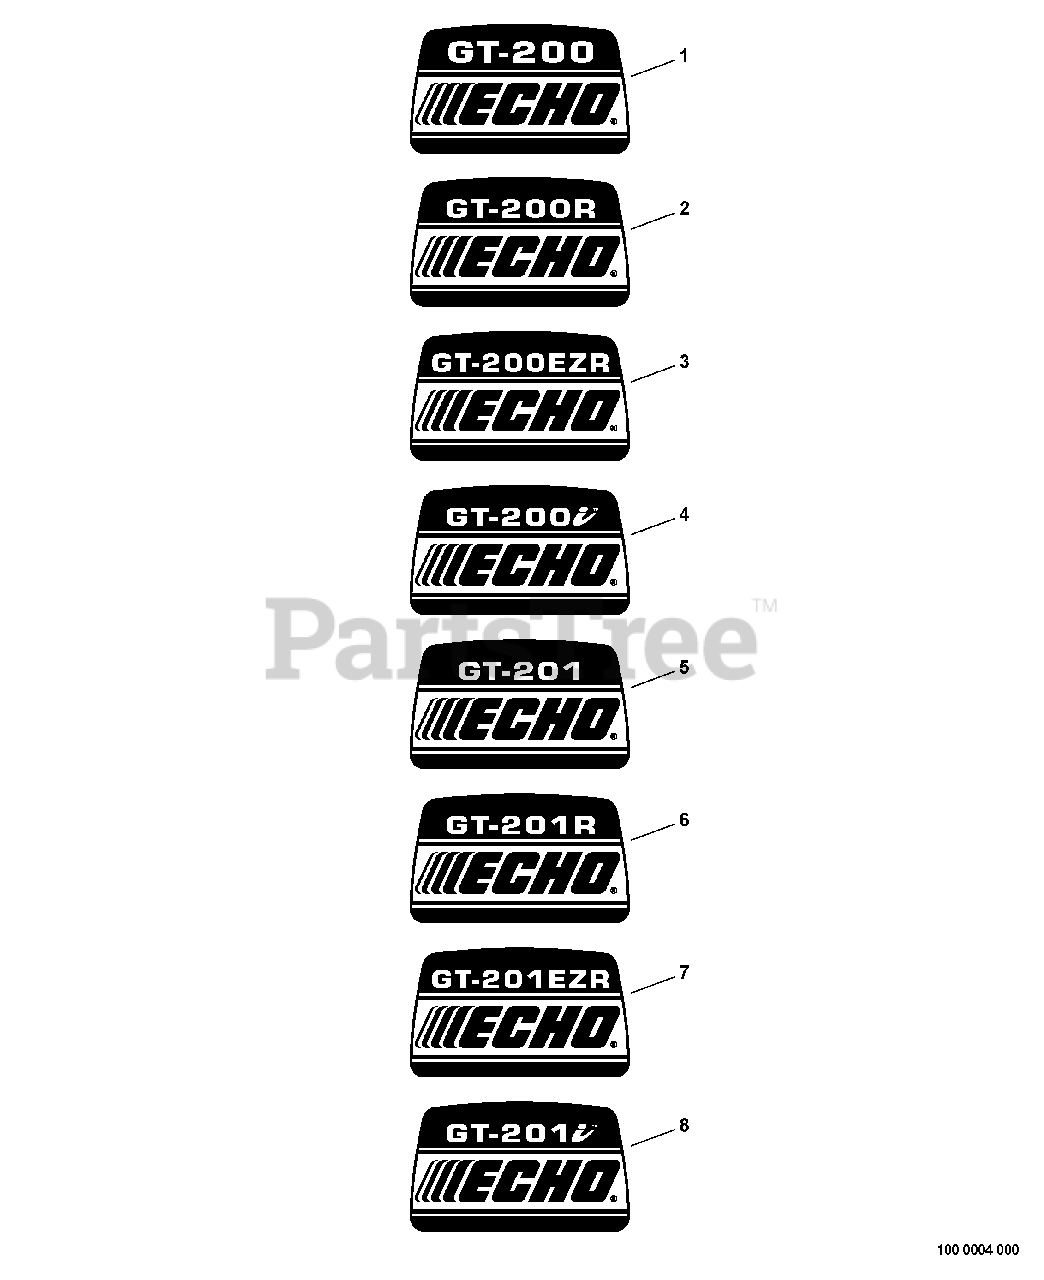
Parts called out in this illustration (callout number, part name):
1	LABEL - MODEL GT-200
2	LABEL - MODEL GT-200R
3	LABEL - MODEL GT-200i
4	LABEL - MODEL GT-200i
5	LABEL - MODEL GT-201
6	LABEL - MODEL GT-201R
7	LABEL - MODEL GT-201i
8	LABEL - MODEL GT-201i
